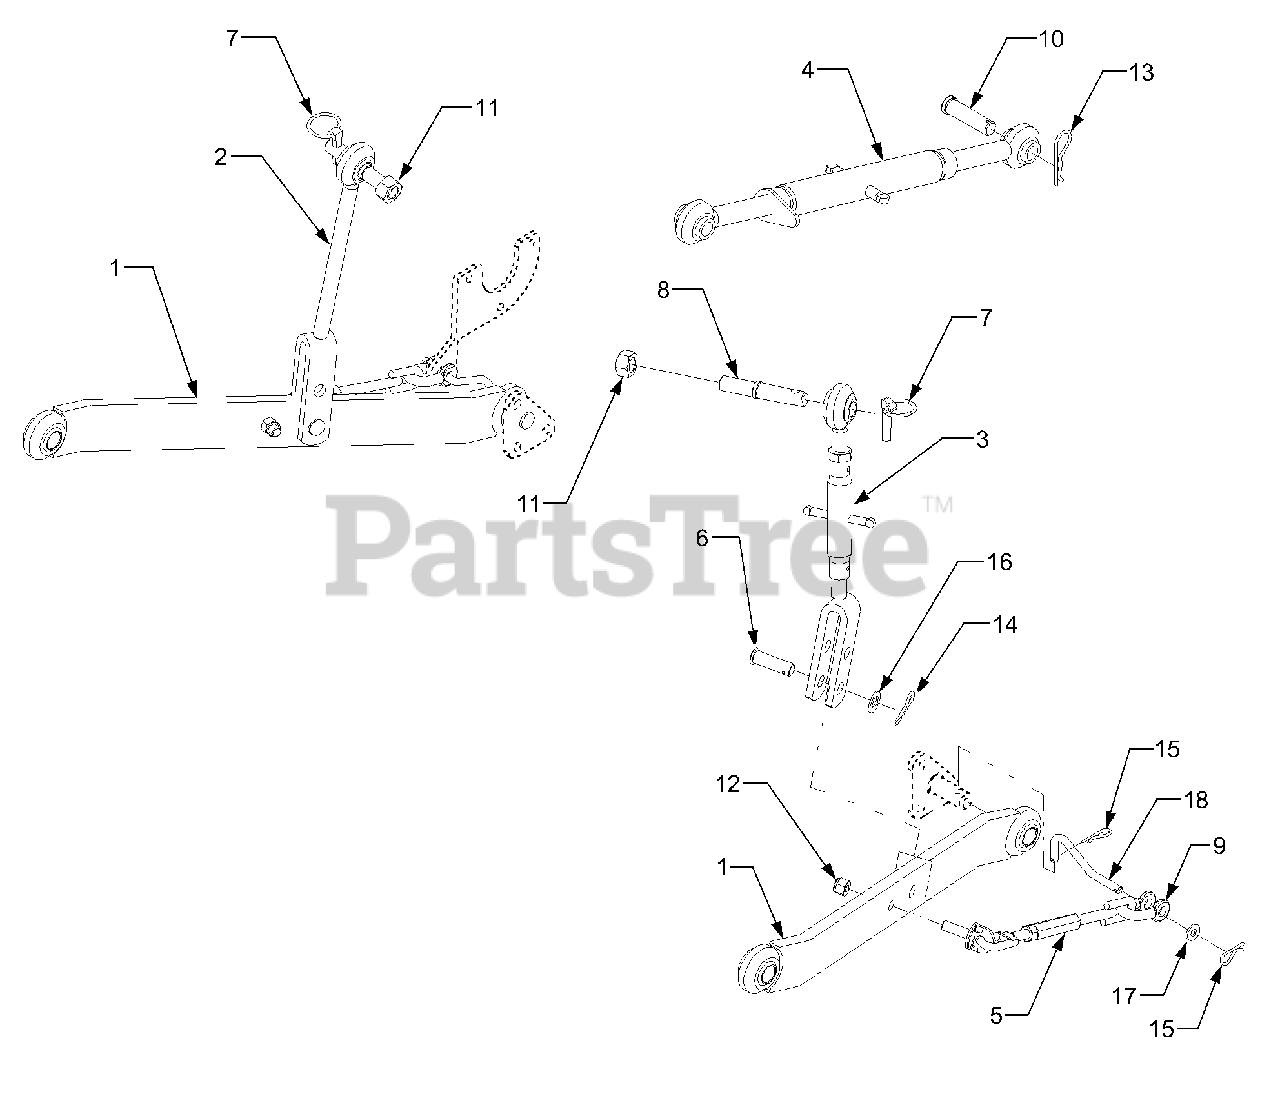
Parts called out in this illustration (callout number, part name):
3	Link, Lift - Adjustable
4	Link, Upper Center
5	Chain Assembly, Check
6	Pin, Clevis, .624 Dia
7	Pin, Klik, 1.75 Lg.
8	Pin, Upper Lift Arm
9	"U" Clevis, Check Chain
10	Pin, Clevis, .75 x 2.75
11	Nut, Hex, 3/4-16 GR8
12	Nut, Hex Insert Lock, 1/2-20
13	Pin, Internal Cotter, .148 x 3.0
14	Pin, Internal Cotter, .125 x 1.75
15	Pin, Internal Cotter
16	Washer, Flat, .635 x 1.12 x .09
17	Washer, Flat, .385 x .87 x .09
18	Pin, Double Clevis
